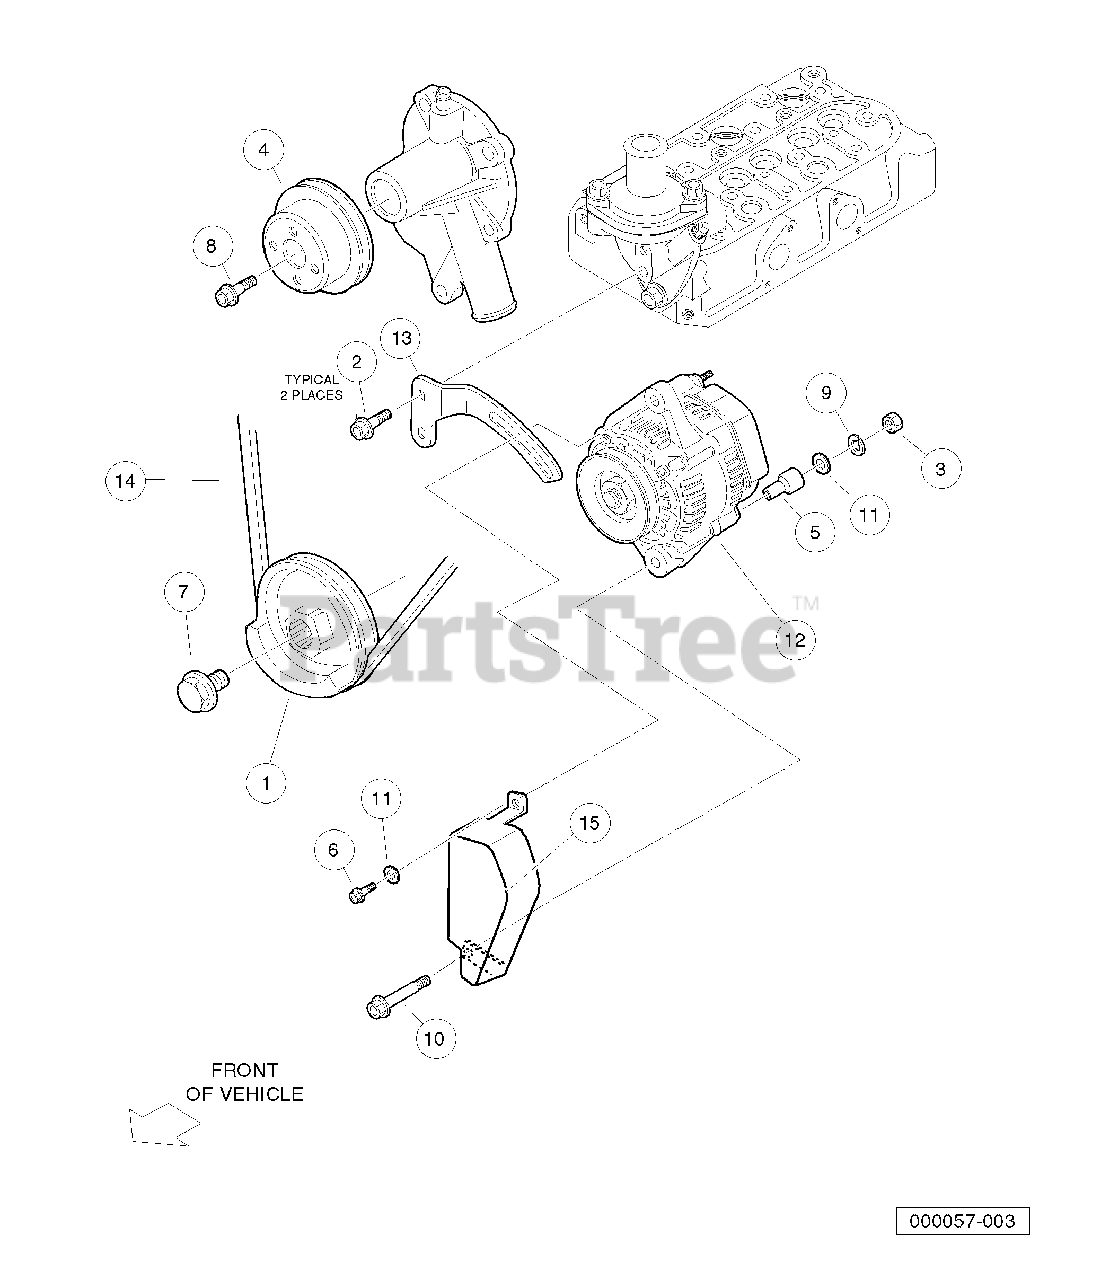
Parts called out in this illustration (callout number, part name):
1	Pulley, Fan Drive
2	Bolt, M6 X 1 X 20
3	Nut, M8, Plate
4	Pulley, Water Pump
5	Collar, Alternator Assy, D722
6	Bolt, Alt, D722, Adjuster
7	Bolt, Alt, D722, Drive Pulley
8	Bolt, D722, Drive Pulley
9	Washer, Spring, D722, Starter
10	Bolt, Alternator, Lower
11	Washer, Alternator, Upper
12	Alternator, 60 Amp
13	Brkt, Alt, D722, 60 Amp
14	Belt, Acc Drive, D722, 60 Amp
15	Guard, Ace Belt
